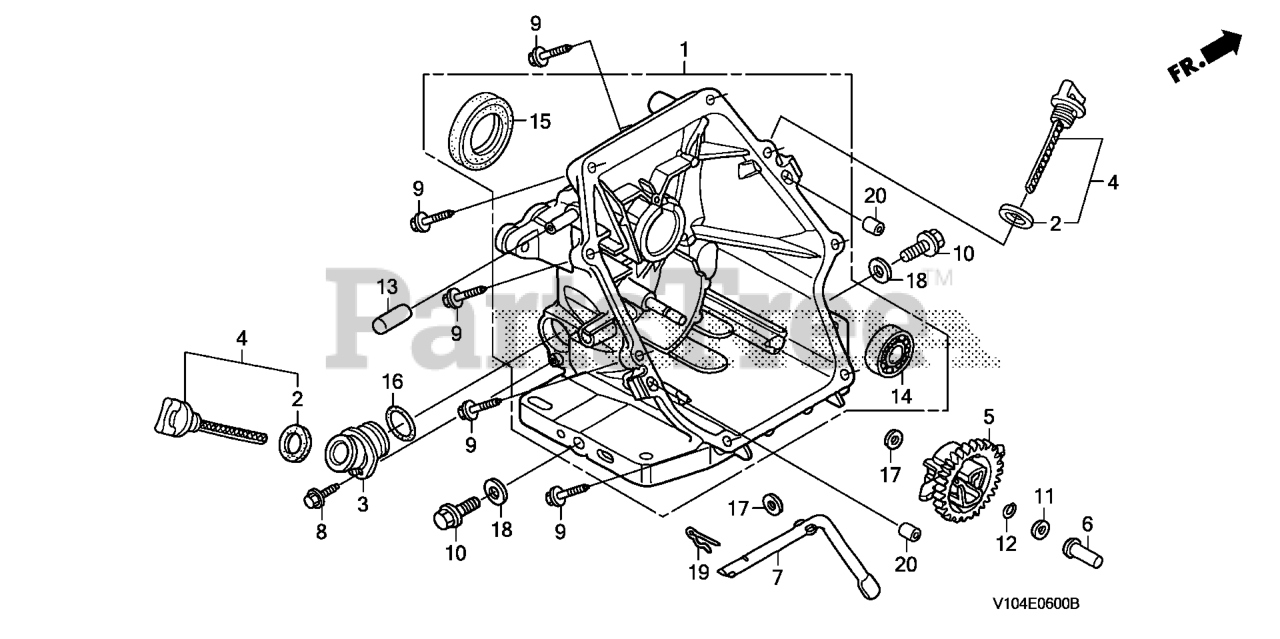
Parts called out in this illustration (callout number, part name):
1	COVER ASSY., CRANKCASE
2	GASKET, OIL FILLER CAP (NOT AVAILABLE)
3	EXTENSION, OIL FILLER
4	GAUGE ASSY., OIL LEVEL
5	GOVERNOR ASSY.
6	SLIDER, GOVERNOR
7	SHAFT, GOVERNOR ARM
8	BOLT, FLANGE (6X14) (CT200)
9	BOLT, FLANGE (6X25) Use up to Engine SN 2056819.
10	BOLT, DRAIN PLUG
11	WASHER, THRUST (6MM)
12	CLIP, GOVERNOR HOLDER
13	CAP, SEALING
14	BEARING, RADIAL BALL (62/28)
15	OIL SEAL (28X41.25X6)
16	O-RING (22.5X2.2) Use from Engine SN 1257295.
17	WASHER, PLAIN (6MM)
18	WASHER, DRAIN PLUG (12MM)
19	PIN, LOCK (8MM)
20	PIN, DOWEL (8X20)
